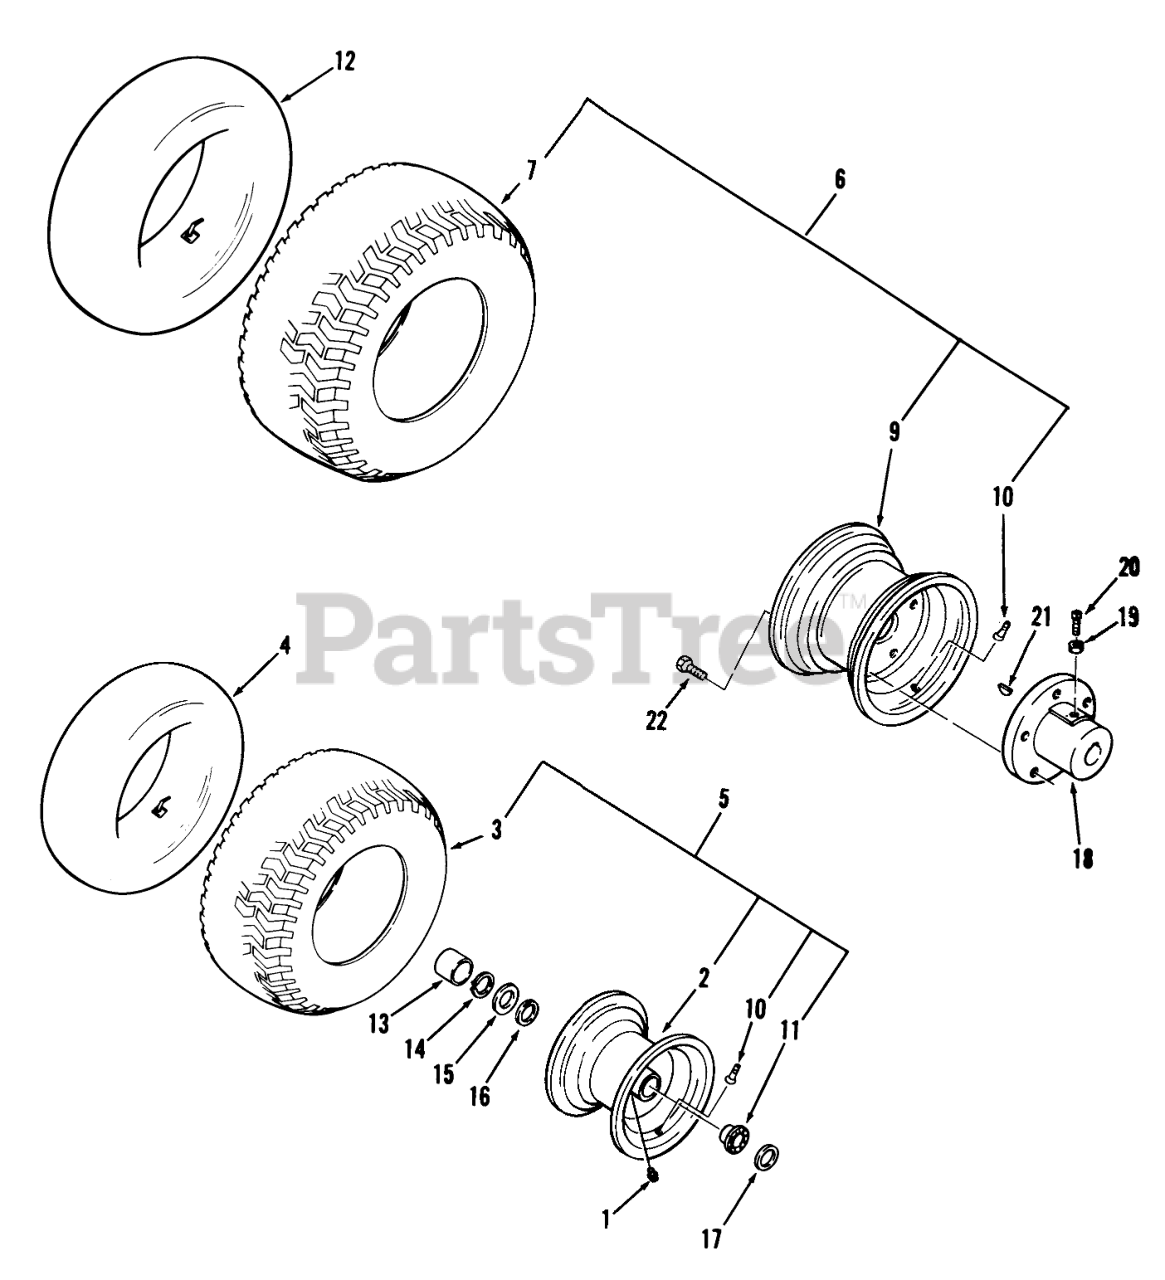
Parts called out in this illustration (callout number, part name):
1	Zerk
2	Front Wheel
3	Front Tire 16 x 6.50-8
4	TUBE-INNER
5	Wheel & Tire Assy-Front
6	Wheel & Tire Assy-Rear
7	TIRE 22 X 7.50-12
9	Rear Wheel
10	VALVE
11	Ball Bearing
12	INNER TUBE
13	HUB CAP-FLAT BLACK
14	Snap Ring
15	WASHER-WHEEL
16	WASHER
17	WASHER-SHIM
18	Hub-Rear
19	Nut
20	Screw-Set
21	WOODRUFF KEY
22	Lug Nut
